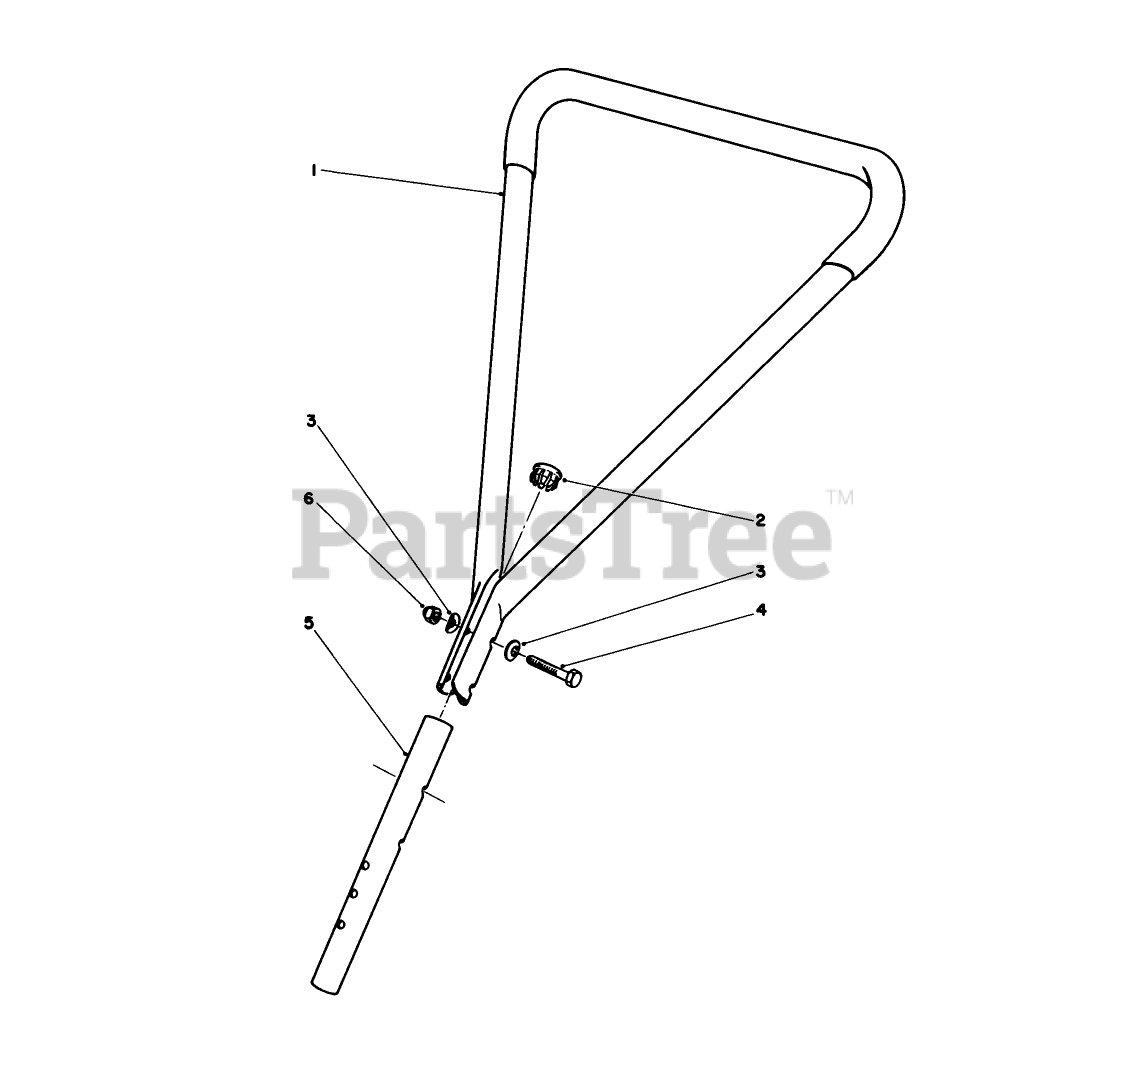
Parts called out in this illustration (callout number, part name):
3	WASHER
4	SCREW-HH
6	NUT-CAP
